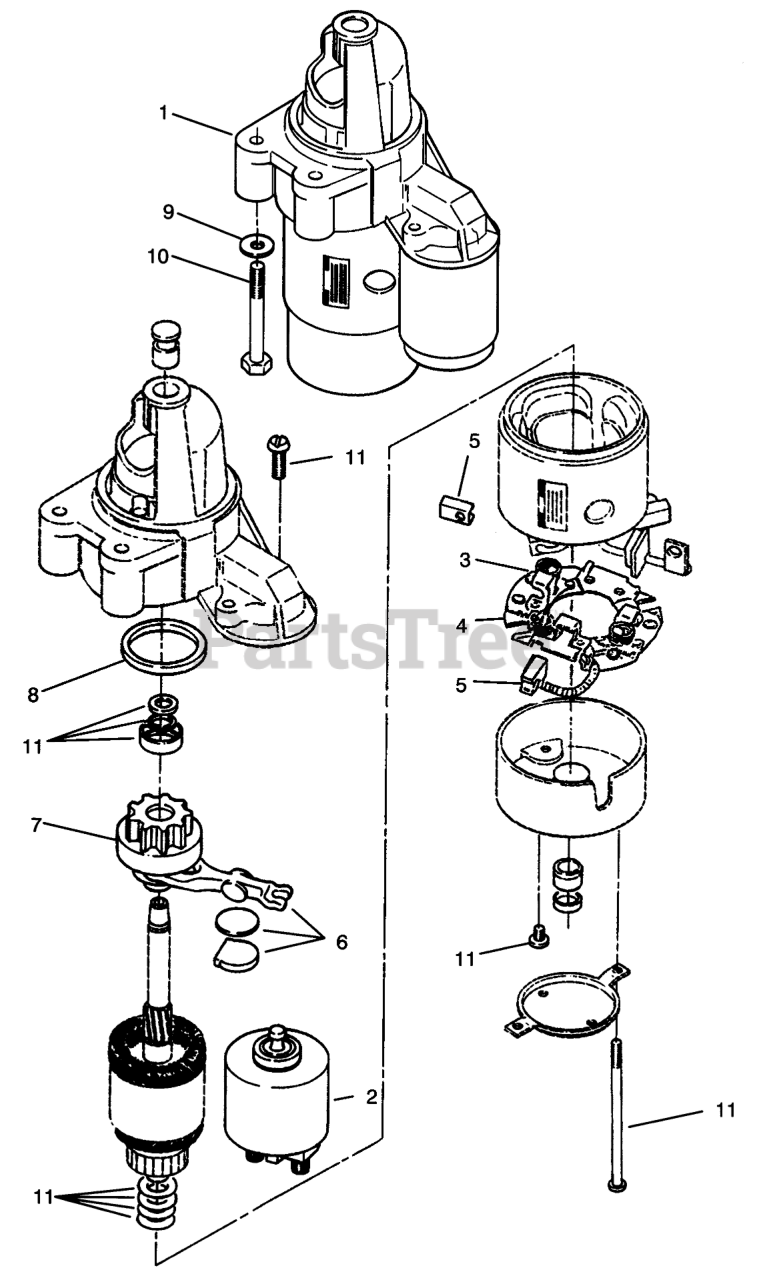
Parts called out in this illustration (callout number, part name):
1	Starter Assy
2	Kit-Starter Solenoid (Incl. Spring Plunger)
3	SPRING-BRUSH
4	Holder-Brush (Incl. Negative Brush)
5	Kit-Brush (Incl. Positive Brush (2) & Negative Brush w/Pigtail)
6	Kit-Starter Shift Lever (Incl. Wear Plate & Plug)
7	Clutch-Starter (Incl. Pinion Gear w/Clutch)
8	Dust Seal
9	WASHER
10	Bolt
11	Kit-Hardware (Incl. Solenoid Screws (2) Brush Holder Screws (2) Thru Bolts (2) Armature Shims (2) Pinion Stop Collar & Pinion Retaining Ring)
